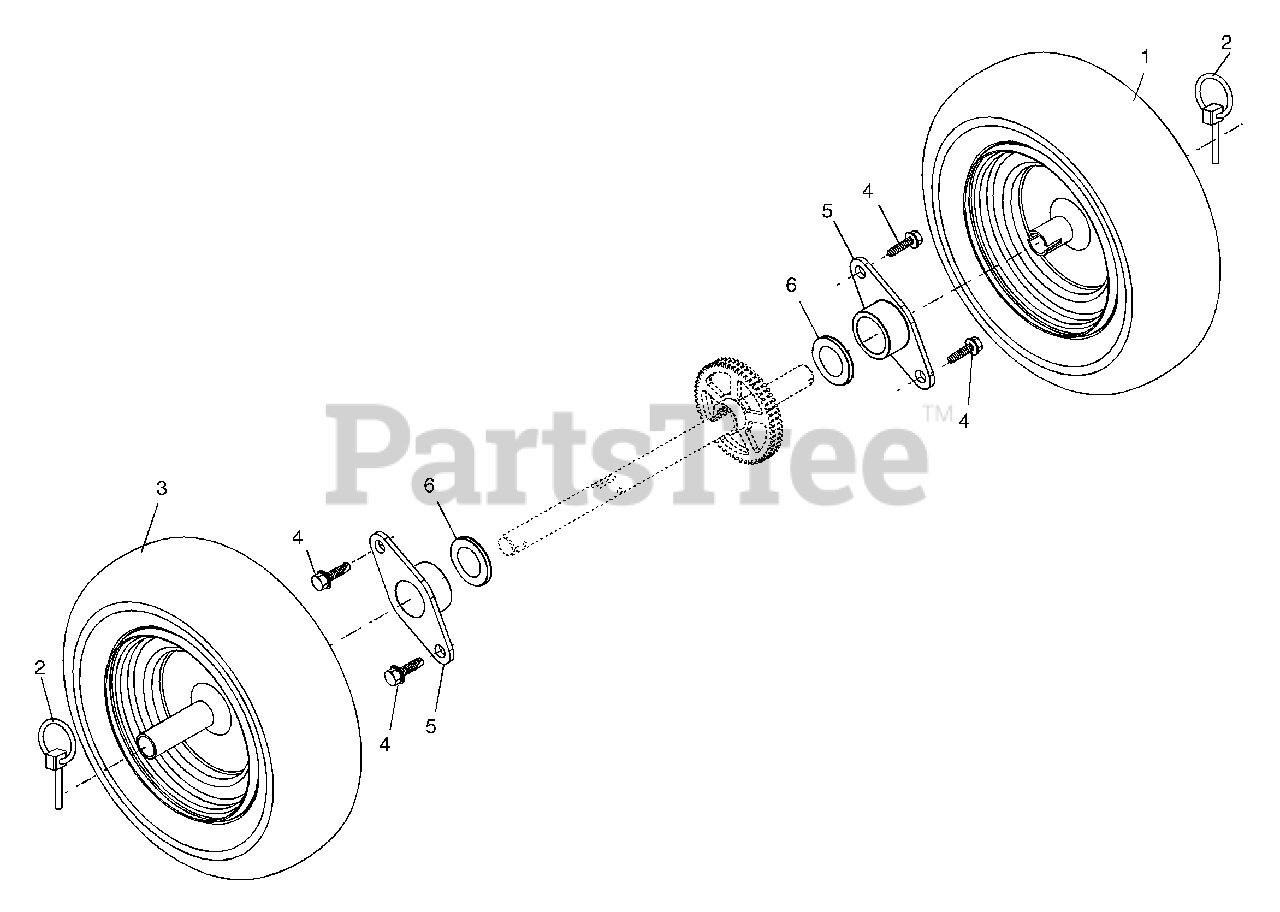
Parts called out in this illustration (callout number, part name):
1	Wheel Assembly, 13", LH
2	Pin, Klik 1/4
3	Wheel Assembly, 13", RH
4	Screw, Hex Head 5/16-18 x 1/2
5	Bearing, Axle
6	Washer, Thrust (1")
